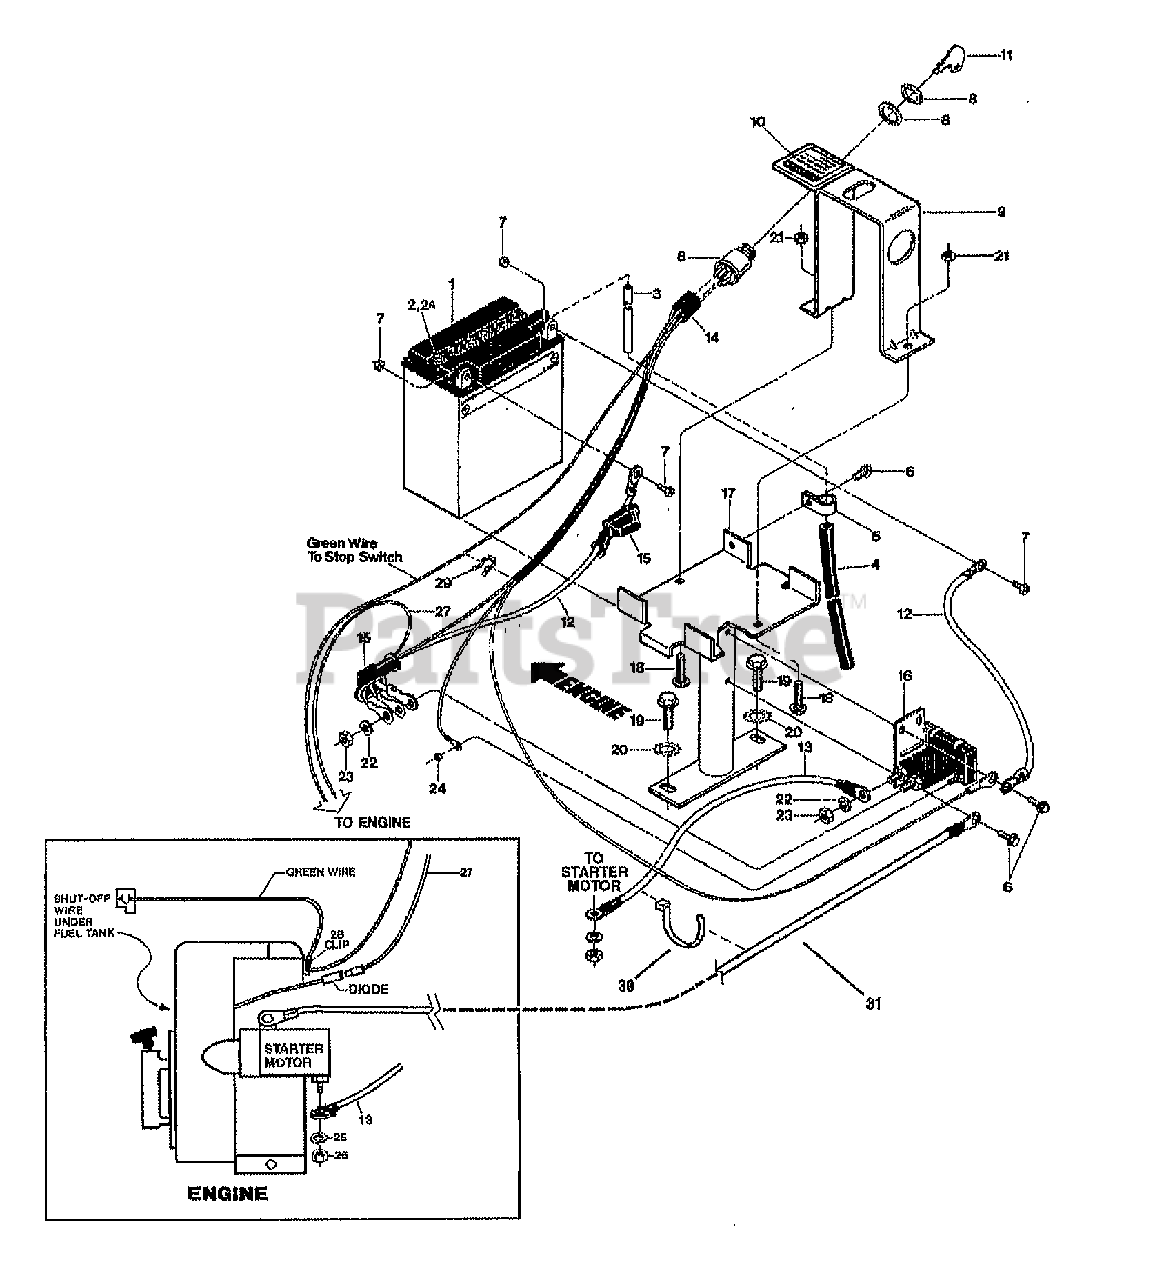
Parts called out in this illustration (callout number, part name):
1	BATTERY
2	CAP-YELLOW
2A	CAP-BATTERY WHITE (PONY)
3	TUBE-VENT BATTERY/HSE
4	TUBING-RUBBER
5	CLAMP
6	SCR-HWH 1/4-20 X .5 STH
7	HDW PKG-BATTERY TERMINAL
8	ASSM-KEYSWITCH ELEC TLR
9	KEYSWITCH W/DECAL PONY
10	DECAL-IGNITION TILLERS
11	KEYS-IGN T/BLAZER 1 PAIR
12	CABLE-BATTERY-12"
13	CABLE-BATTERY 12"
14	KIT-WIRE HARNESS ASSM (AVAILABLE AS COMPLETE ASSEMBLY ONLY)
15	BOOT-BATTERY CABLE
16	SOLENOID
17	BRKT-BATTERY OPC PNT
18	NUT-WELD 5/16-18
19	SCR-HFLK 5/16-18X1.00 ZP
20	WASHER-LK .312 EXT TOOTH
21	NUT-HF/LK 1/4-20 ZP
22	WASHER-LK .312 ZP
23	NUT-HEX 5/16-24
24	NUT W/LKWASHER #10-32 ZP
25	LOCKWASHER
26	NUT
27	WIRE-RECHARGE 5&7 BRIGGS
28	CLIP-SPECIAL
29	TIE-TWIST LOCK
30	TIE-RED
31	CABLE-BATTERY 15"
